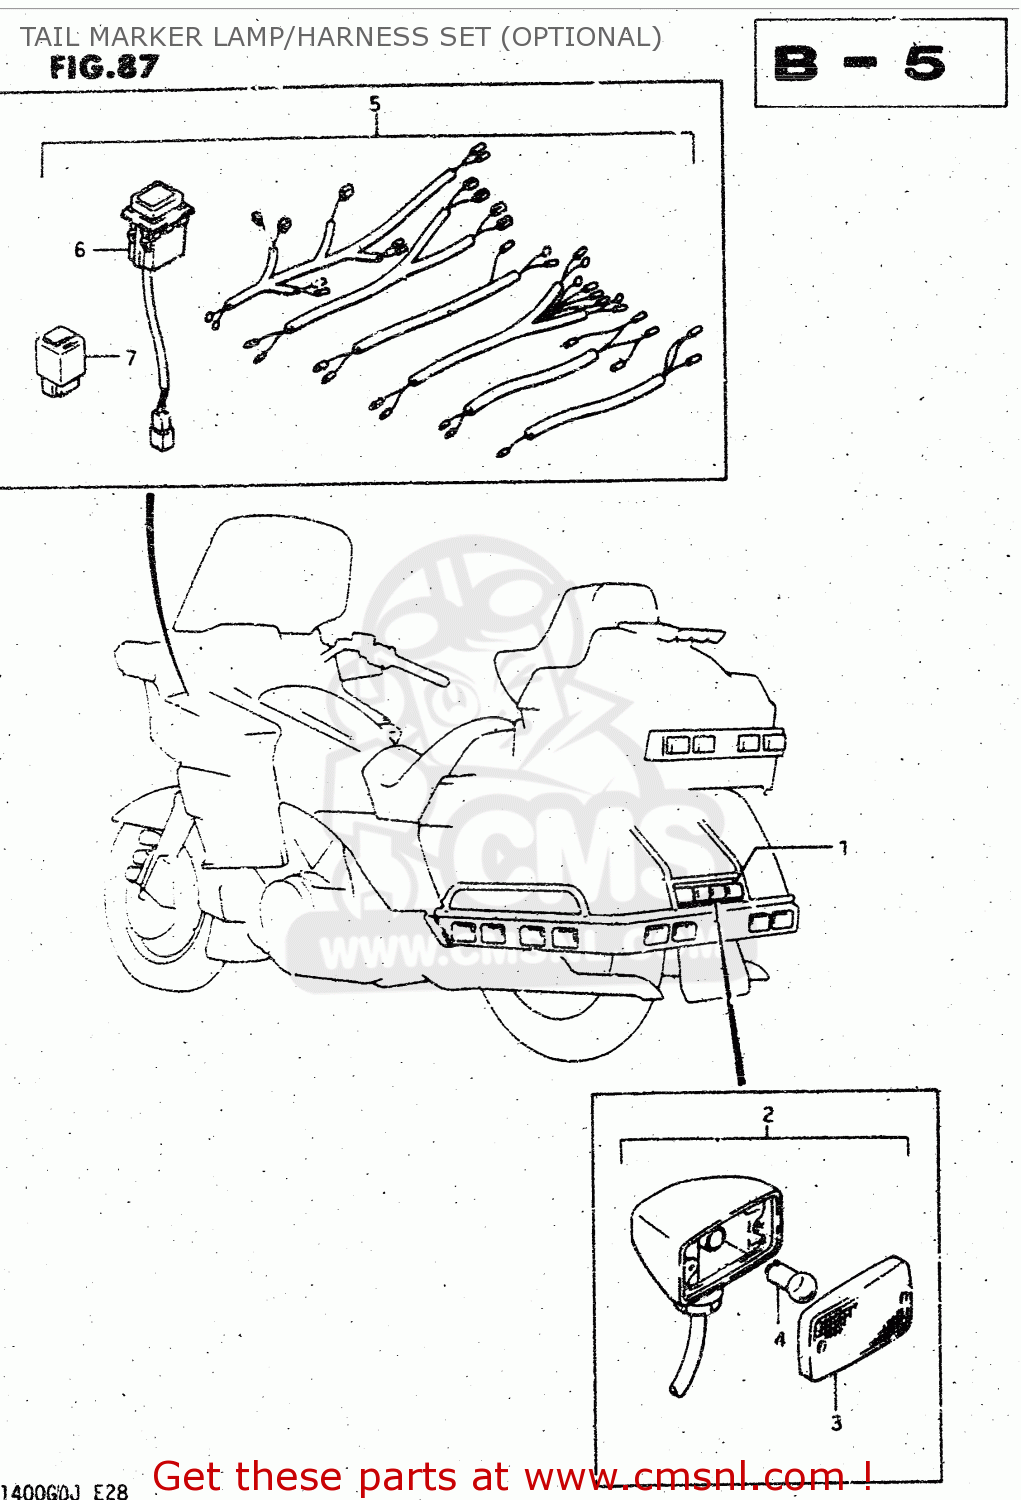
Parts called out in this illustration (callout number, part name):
1	REAR END,MARKER LAMP S
2	TRAVEL TRUNK,MARKER LAMP
3	LENS
4	BULB 12V 3W
5	MARKER LAMP SWITCH & WASHER
6	SWITCH ASSEMBLY,LIGHTING
7	RELAY ASSY, MARKER LAMP
